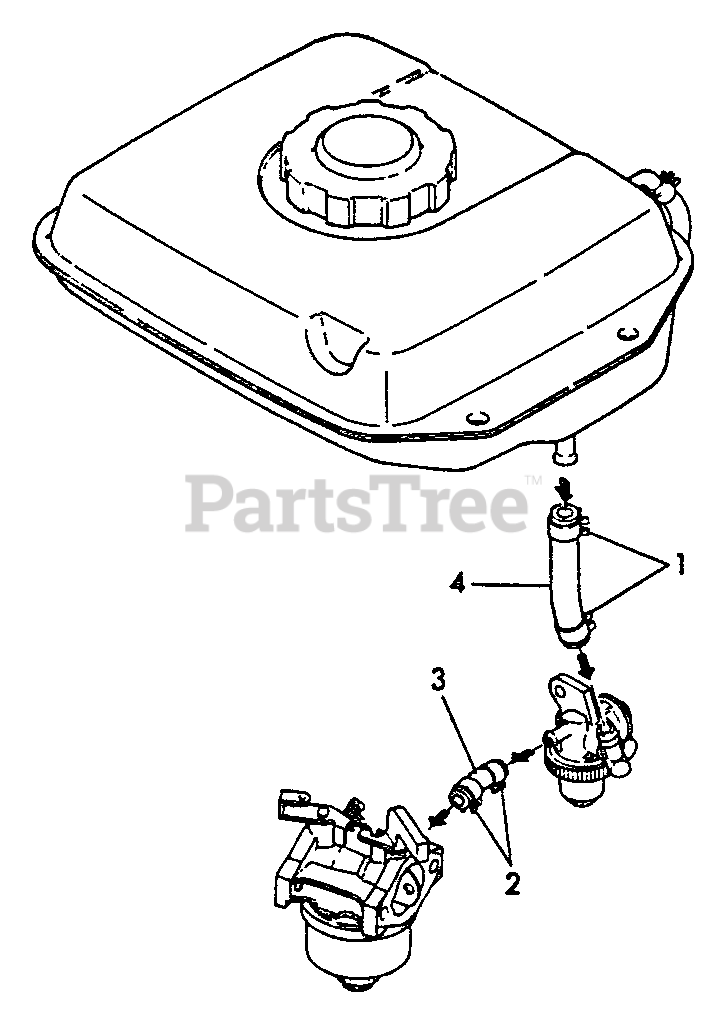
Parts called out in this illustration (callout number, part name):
1	CLAMP, HOSE
2	CLAMP, HOSE - 9
3	PIPE, FUEL
4	PIPE, FUEL
